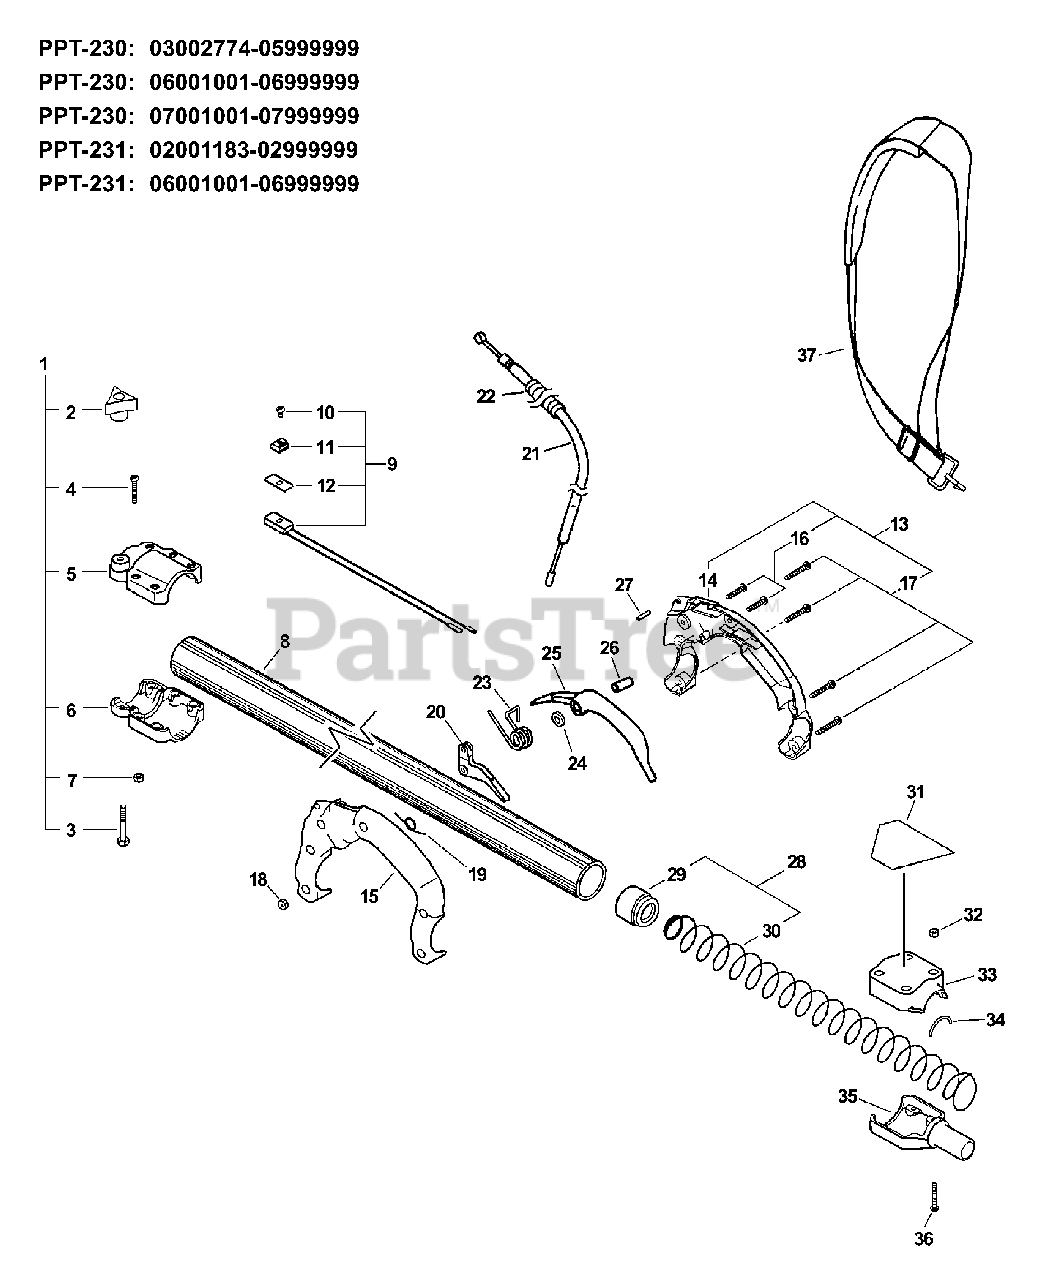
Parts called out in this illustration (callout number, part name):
1	CLAMP ASSY
2	THUMBSCREW
4	SCREW, TORX 10-24 UNC 1-1/4
5	COLLAR, UPPER
6	COLLAR, LOWER
7	NUT, LOCK 10-24 UNC
8	PIPE, MAIN
9	SWITCH, ON-OFF
10	SCREW 3×10
11	KNOB, SWITCH - ORANGE
12	LABEL, SWITCH
13	HANDLE SET, REAR
14	HANDLE, LEFT REAR
15	HANDLE, RIGHT REAR
16	SCREW, TORX 10-24 UNC 1-1/4
17	SCREW, TORX 10-24×1.5
18	NUT, LOCK 10-24 UNC
19	SPRING, TORSION
20	TRIGGER, THROTTLE
21	CABLE, THROTTLE
22	TUBE, FLEXIBLE
23	SPRING, TORSION Ø0.39 I.D.
24	WASHER 5.5×12×0.8
25	LOCKOUT, THROTTLE
26	COLLAR 5.08×14.5
27	PIN, LOCATING 0.17 OD×0.75 L
28	BUSHING ASSY, FLOATING
29	BUSHING, FLOATING
30	SPRING, COMPRESSION
31	LABEL, CAUTION
32	NUT, LOCK 10-24 UNC
33	CAP, MAIN PIPE
35	ADAPTER, LOWER SHAFT TUBE
36	SCREW, TORX 10-24×1.5
37	STRAP ASSY, SHOULDER
